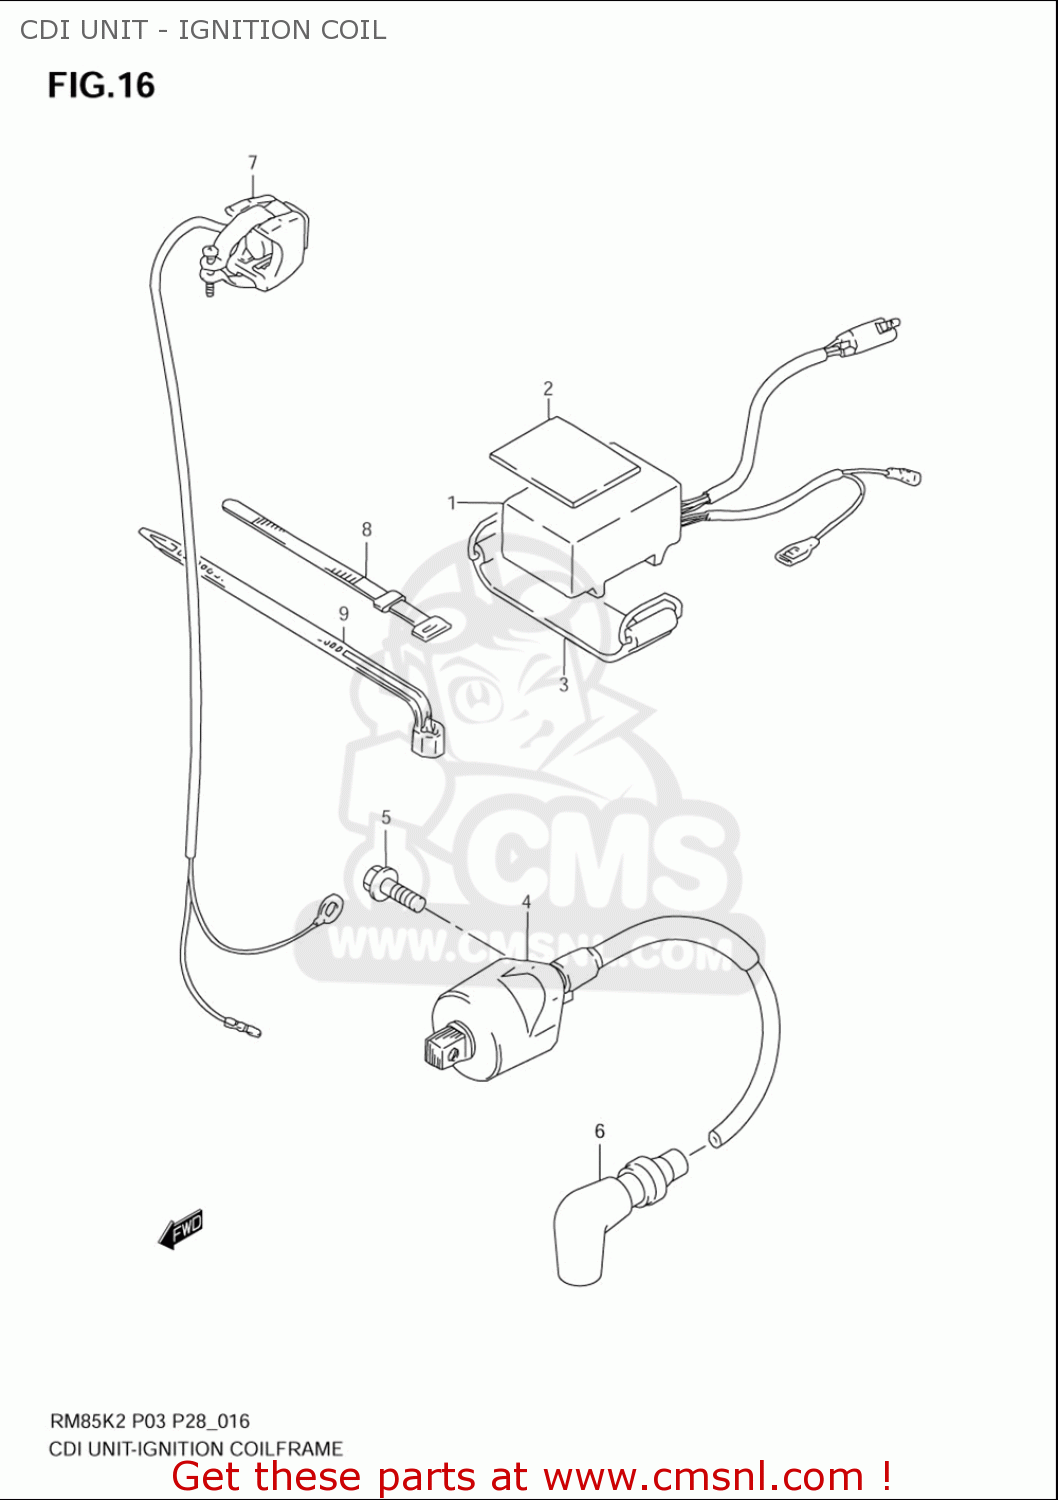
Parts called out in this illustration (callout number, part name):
1	CDI UNIT
2	PROTECTOR(170X95X3.0)
3	BAND
4	COIL ASSY,IGNITION
5	BOLT,6X20
6	CAP,SPARK PLUG
7	SWITCH ASSY,ENGINE STOP
8	CLAMP(L:120)
9	CLAMP(L:90)
